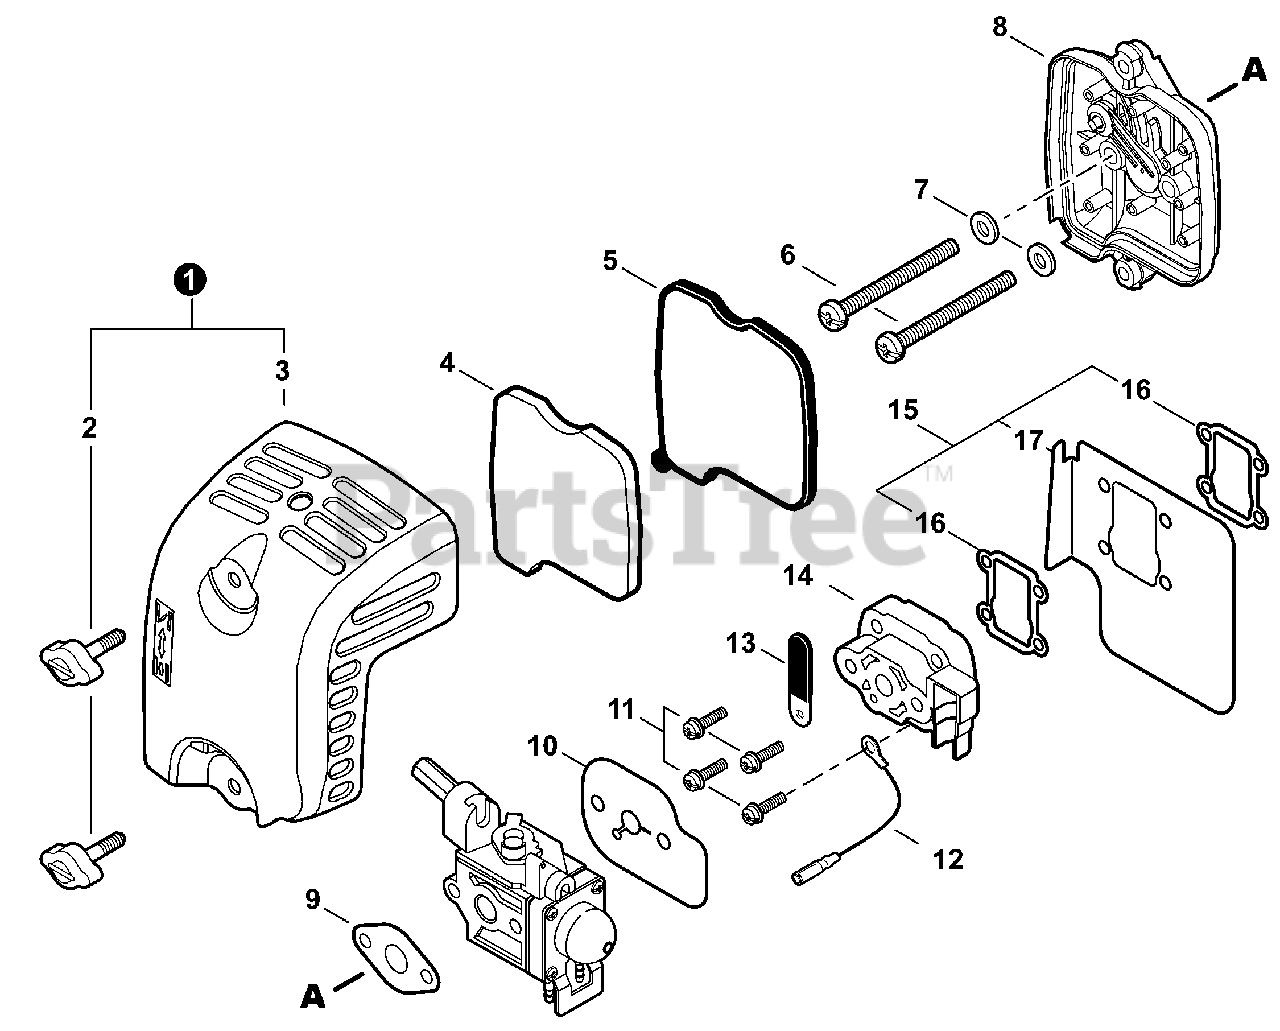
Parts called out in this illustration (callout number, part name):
1	COVER ASSY, AIR FILTER
2	THUMBSCREW
3	COVER, AIR FILTER
4	PRE-FILTER, FOAM
5	FILTER, AIR
6	SCREW M5×60
7	WASHER 5.5×12×0.8
8	CASE, AIR FILTER
9	GASKET, INTAKE
10	GASKET, INTAKE
11	SCREW M5×22
12	LEAD - GROUND L= 110mm
14	INSULATOR WITH REED VALVE
15	SHIELD ASSY, INTAKE HEAT
16	GASKET, EXHAUST
17	HEAT SHIELD, INTAKE
